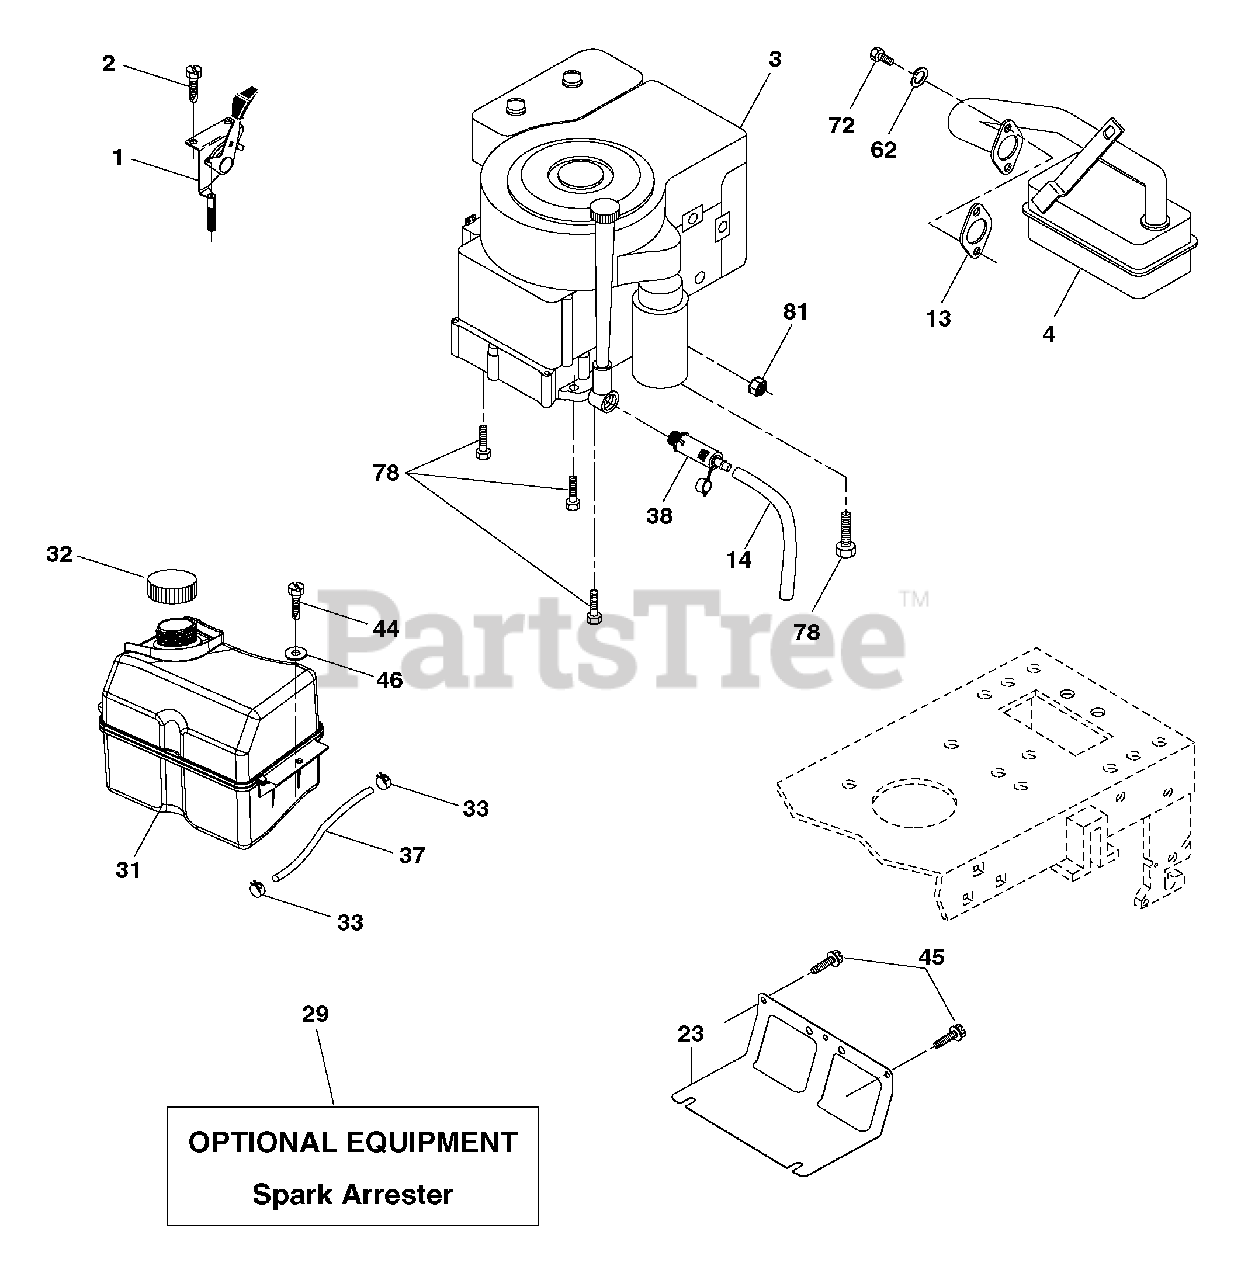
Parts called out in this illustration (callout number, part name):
1	Control, Throttle
2	Screw Hex Thd Cut 1/4-20 x 1/2
4	Muffl er
13	Muffl er Gasket
14	Tube Oil Drain
23	Shield, Browning/Debris Guard
29	Arrester, Spark
31	Tank, Fuel
32	Cap, Fuel
33	Clamp, Hose Blk
37	Line, Fuel
38	Plug Drain Oil Easy
44	Screw Hex Wsh Thdrol 1/4-20 x 3/4
45	Screw Hex Wsh Thdrol 3/8-16 x 3/4
46	Washer 9/32 x 7/8 x 16 Ga.
62	Washer Split
72	Screw Socket Hd 5/16-18 x .75
78	Screw 3/8-16 x 1-1/4
81	Nut Keps Hex 1/4-20 unc
